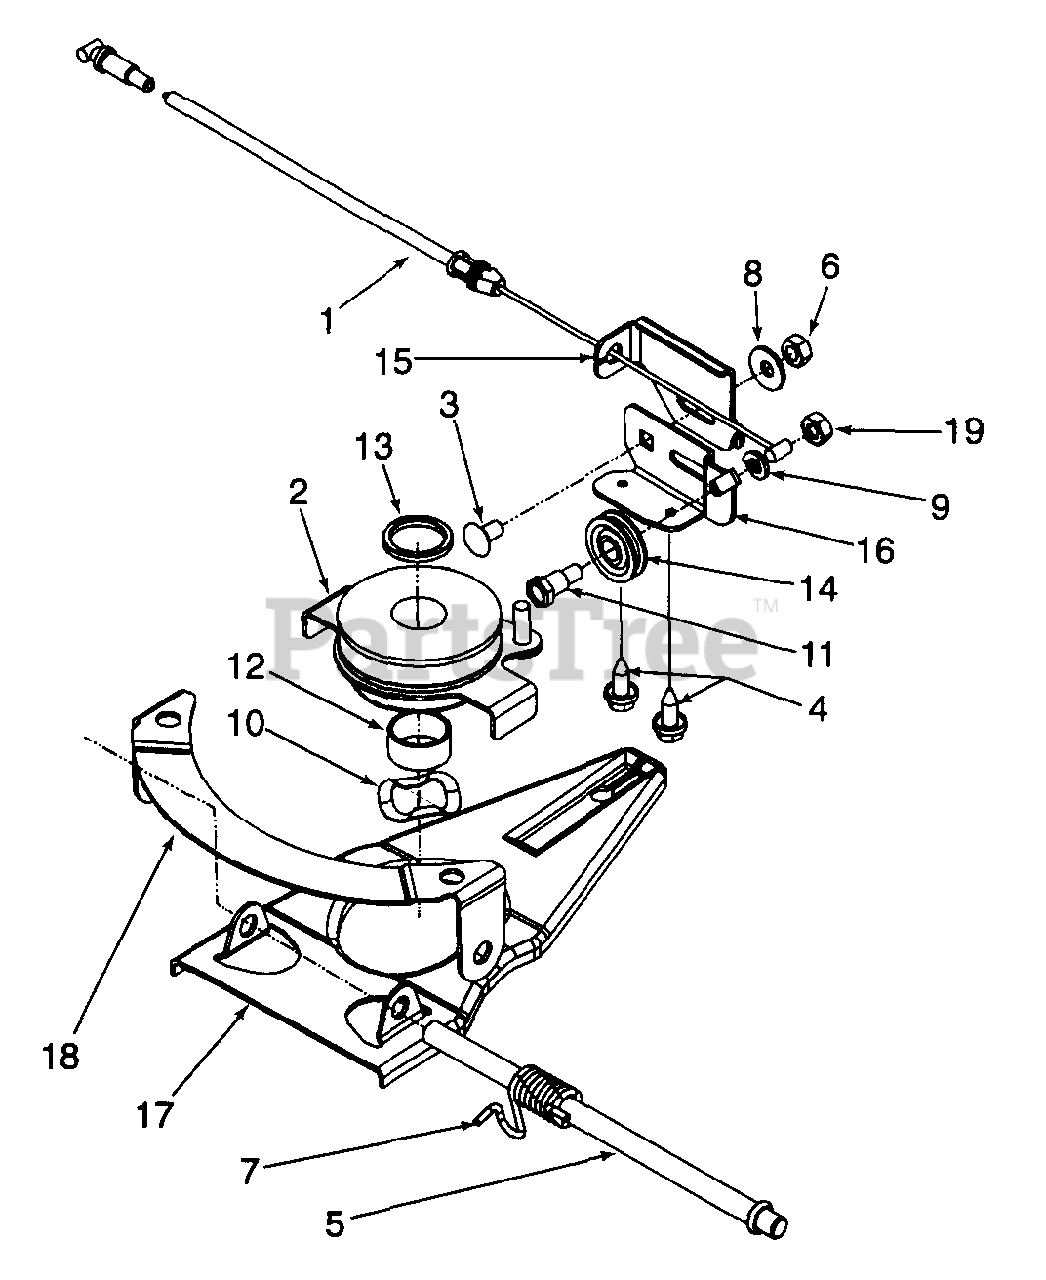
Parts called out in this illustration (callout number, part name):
1	6 Spd. Cable
2	Pulley Ass'y Multi- Spd.
3	Scr. 1/4-20 x .50 Carr.
4	Scr. AB 1/4-14 x .625 Hxinwsh
5	Pivot Shaft
6	Nut 1/4-20
7	Torsion Spring LH
8	Bell Wash. .265 x .75 x .062
9	Lock Wash. 1/4 Reg Duty
10	Wave Wash. 1.38 x .88 x .029
11	Shld. Scr. .340 x .350 x 1/4-20
12	Slev Spcr .88 ID x 1.00 OD x.48
13	Slev Spcr .88 ID x 1.13 ID x .12
14	Roller Cable
15	6 Spd. Cable Adj. Bracket
16	6 Spd. Cable Mt. Bracket
19	Hex Nut 1/4-28
